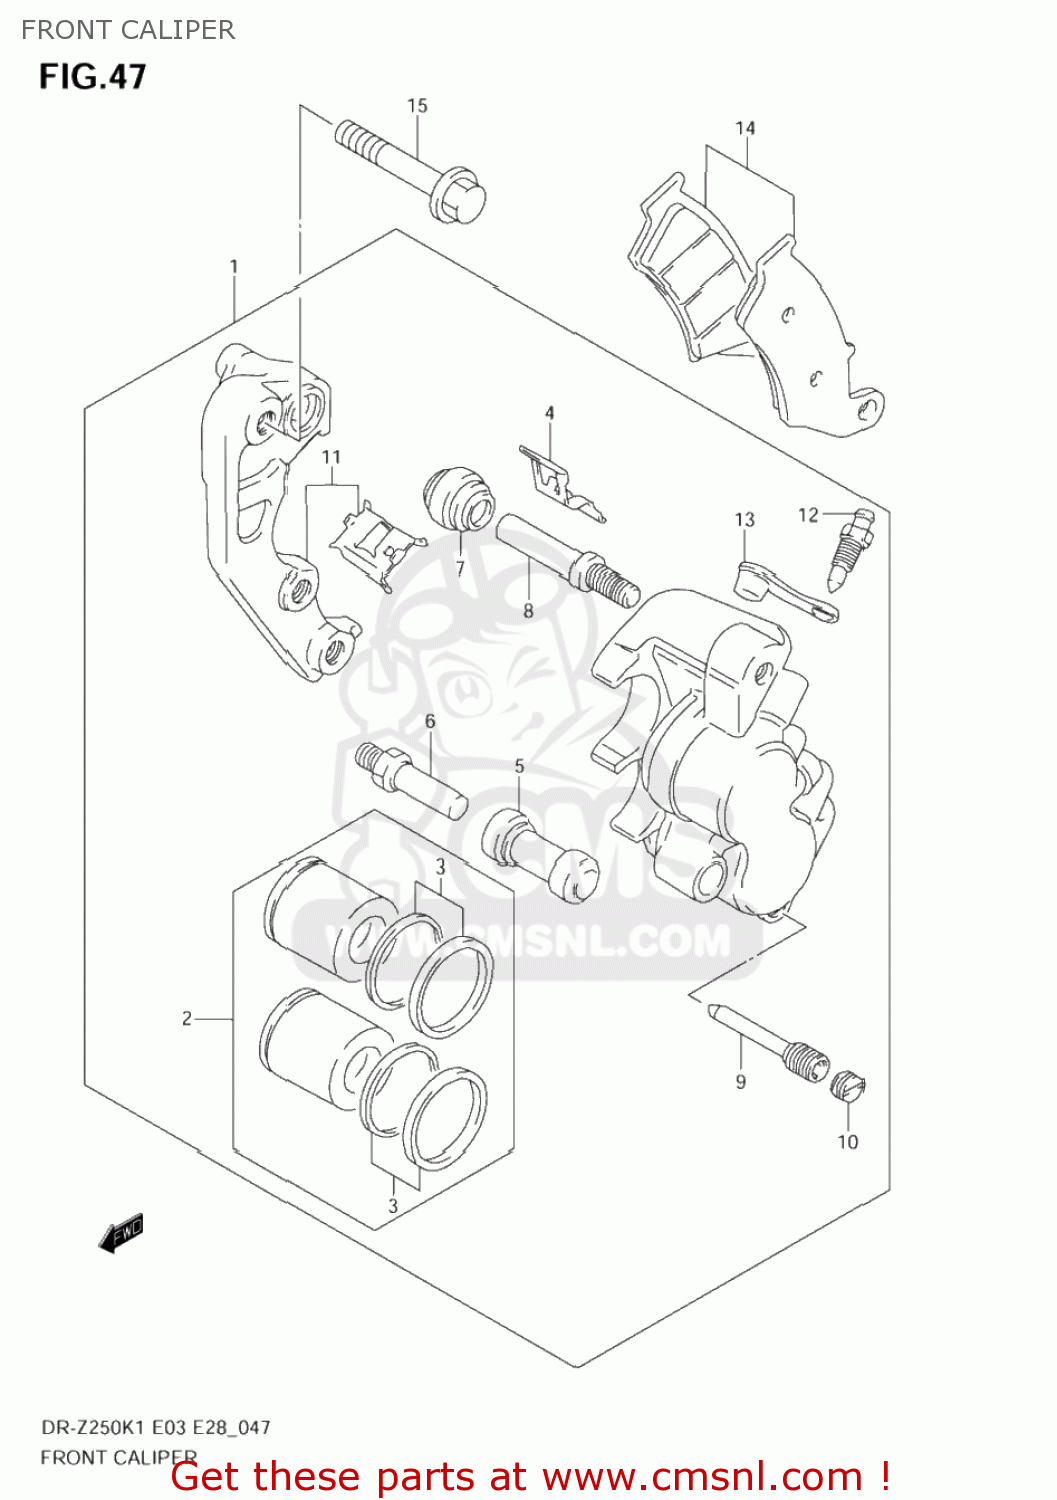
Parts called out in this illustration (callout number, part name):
1	CALIPER ASSY,F
2	PISTON SET
3	SEAL SET,PISTON
4	SPRING,PAD
5	BOOT
6	BOLT
7	BOOT
8	PIN
9	PIN,HANGER
10	PLUG,PIN
11	BRACKET
12	BLEEDER
13	CAP,BLEEDER
14	PAD SET (NAS)
15	BOLT(8X40)
